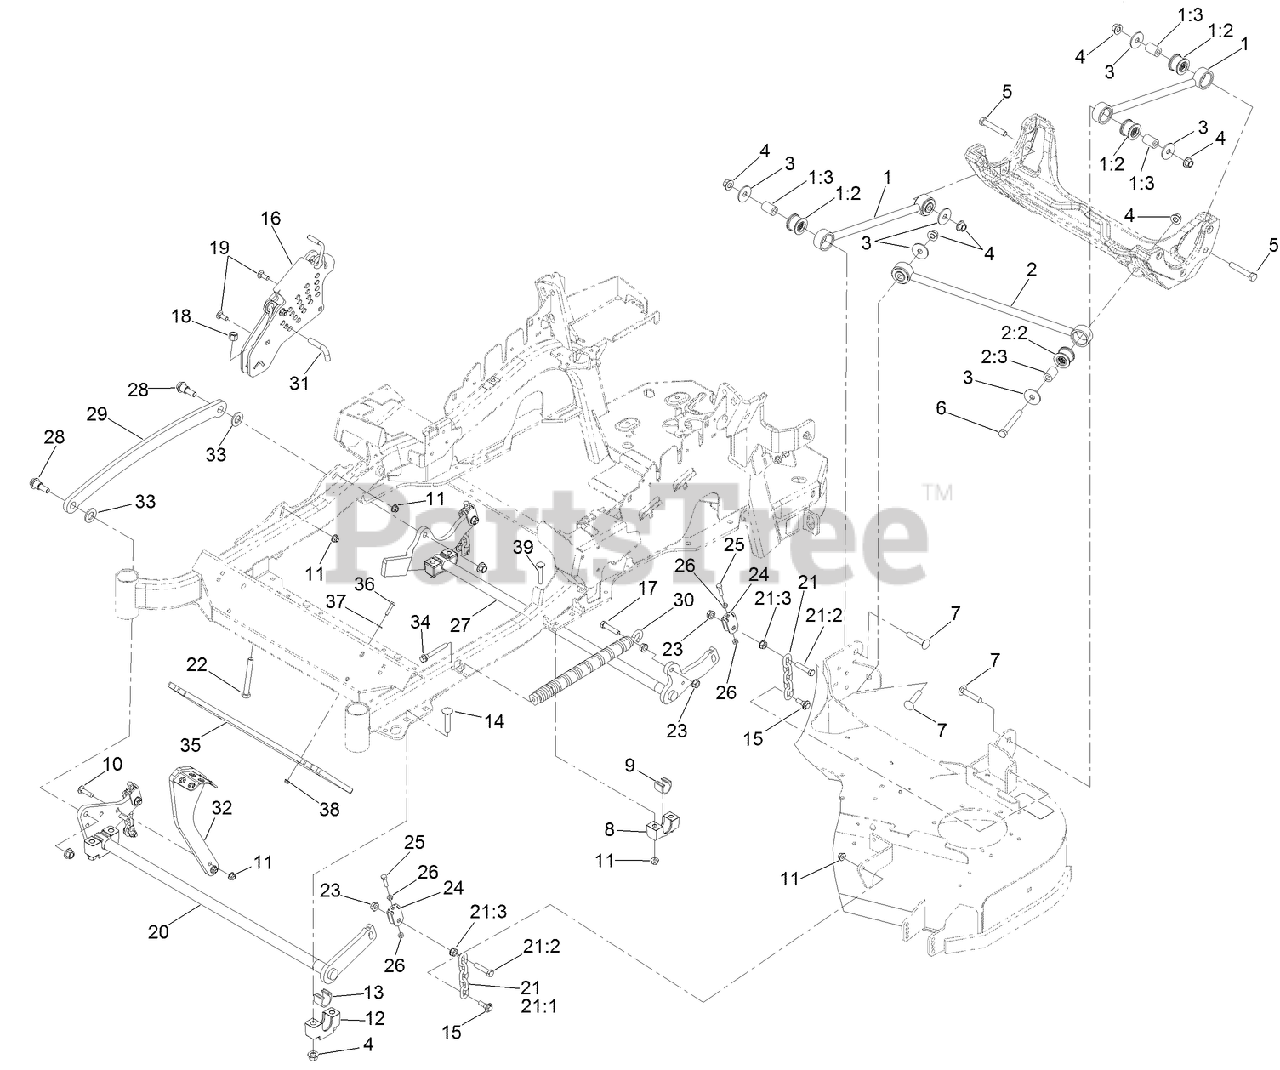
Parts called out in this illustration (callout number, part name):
1	DECK STRUT ASM
1:2	BUSHING-SUSPENSION, RUBBER
1:3	SPACER
2	PANHARD ROD ASM
2:2	BUSHING-SUSPENSION, RUBBER
2:3	SPACER
3	WASHER-THRUST
4	NUT-LOCK
5	SCREW-HH
6	SCREW-HH
7	SCREW-CARR
8	SUPPORT-CROSS SHAFT, BEARING REAR
9	BEARING-CROSS SHAFT, REAR
10	SCREW-HH
11	NUT-HF, NI
12	SUPPORT-CROSS SHAFT, BEARING
13	BEARING-CROSS SHAFT, FRONT
14	BOLT-CARR
15	SCREW-SHOULDER, HHF
16	HOC ASM
17	SCREW-HH
18	NUT-LOCK, NI
19	SCREW-HH
20	DECKLIFT-FRONT
21	DECK LIFT CHAIN ASM
21:1	CHAIN-LIFT, DECK
21:2	SCREW-HH
21:3	NUT-HF
22	BOLT-TAP
23	NUT-HF
24	YOKE-ADJUST, DECK
25	SCREW-HH
26	NUT-JAM
27	LIFT-DECK, REAR
28	SCREW-SHOULDER, HHF
29	LINK-LIFT, DECK
30	SPRING-EXTENSION
31	PIN-HOC
32	LEVER-FOOT
33	WASHER-FLAT
34	BOLT-SHOULDER
35	WEIGHT-TOE BOARD
36	SCREW-HH
37	WASHER-FLAT
38	NUT-HF
39	SCREW-HH
